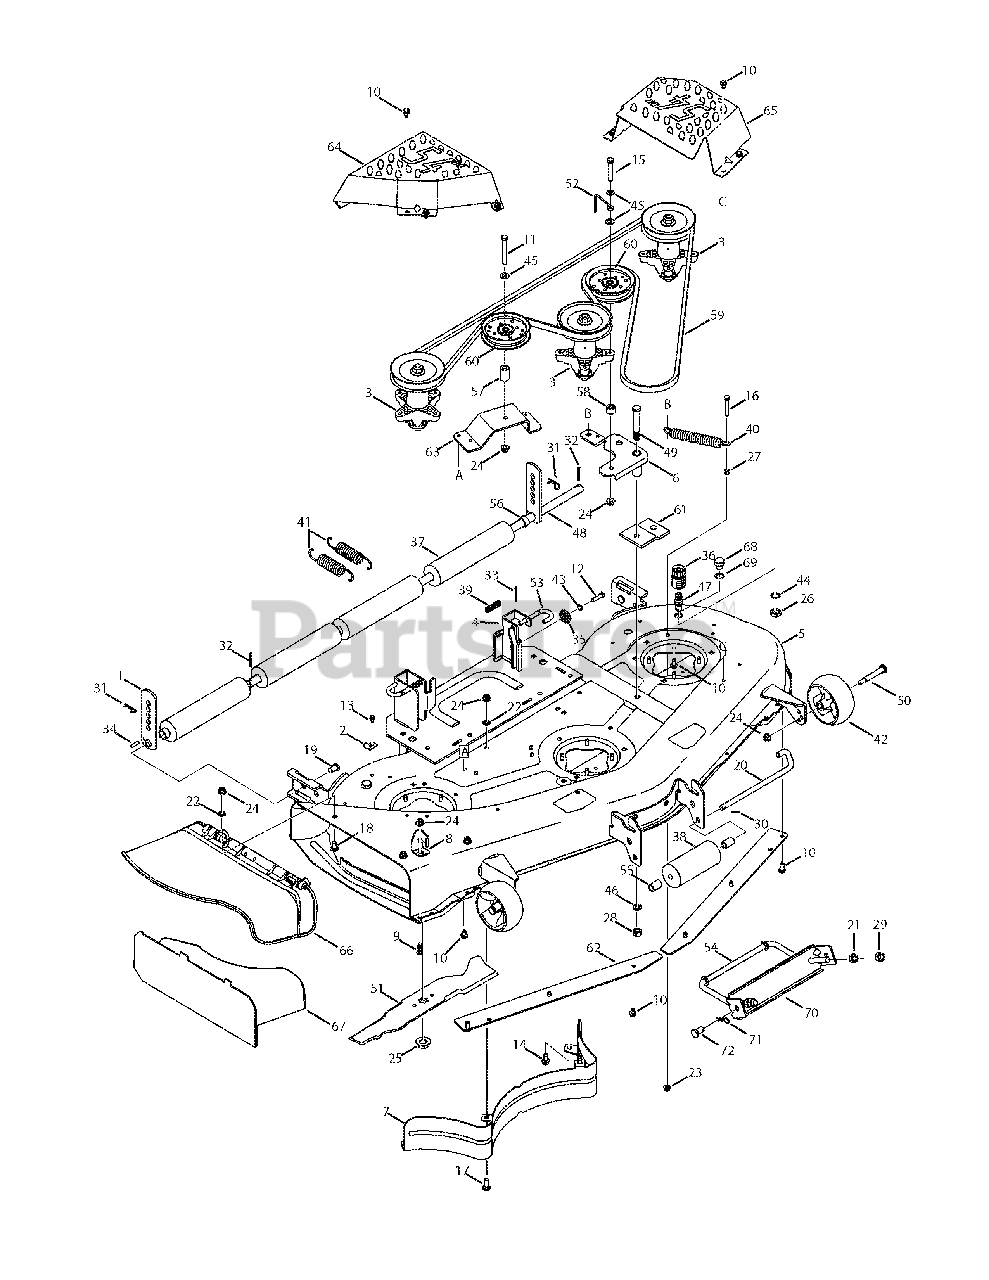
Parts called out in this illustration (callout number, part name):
2	Retainer Hook Brkt.
3	Spindle Assembly
9	Screw, 3/8-16 x 1.0
10	S-Tapp Scr 5/16-18 x .75
11	Screw, 3/8-16 x 3.0
12	Hex Bolt 5/16-18 x 1.25
13	Hex Wash S-Tapp Scr 1/4-20 x .50
14	Screw, 3/8-16 x 0.75
15	Screw, 3/8-16 x 2.5
16	Hex Hd Cap Scr. 5/16-18 x 2.0 Gr. 5
17	Carriage Bolt 3/8-16 x 1.0
18	Short Neck Carriage Bolt 3/8-16 x .75
19	Clevis Pin .50 Dia. x .78
20	Roller Pin .5" Dia x 10.06
21	Hex Nut 1/2-13
22	Push Nut 3/8
23	Flange Locknut 5/16-18 Gr. F, Nylon
24	Flange Lock-Nut 3/8-16 Gr. F Nylon
25	Hex Flange Nut 5/8-18
26	Hex Nut, M16-1.5
27	Hex Nut 5/16-18 hd. (Gr. 5)
28	Hex L-Nut 1/2-13
29	Hex L-Nut 1/2-13
30	Cotter Pin 3/32 x 1.0
33	Cotter Pin 1/8" Dia x 1.25
34	Spring Pin 1/4 Dia. x 1.0
35	Deck Adjustment Gear
36	Water Nozzle Adaptor
38	Front Roller
39	Compression Spring .531 OD x 1.75 Lg.
40	Extension Spring .94 Dia. x 6.74
41	Extension Spring 1.5 x 5.99
42	Deck Wheel 5.0
43	L-Wash 5/16 ID
44	Lockwasher 5/8
45	Flat Washer .406 x .875 x .059
48	Shaft .75 x 47.12
49	Shoulder Screw
50	Shoulder Screw
51	Blade 18.5
52	Idler Belt Keeper Rod
53	Deck Release Pin
54	Deck Adjustment Rod
55	Spacer .55 ID x .75 OD
56	Spacer .82 ID x 1.0 OD x .53
57	Spacer .380 ID x .90 OD x 1.313
58	Spacer .385 ID x .88 OD x .64
59	V-Type Belt, B Section
60	Idler Poulie w/Flange 4.25 Dia
66	Chute Assembly
67	Mulching Plug
68	Plug Bolt, M16 x 1.5
69	Flat Washer .64 x 1.24 x .06
72	Clevis Pin .50 x .78
12650-4008	Height Adjuster - WINE RED (4008)
